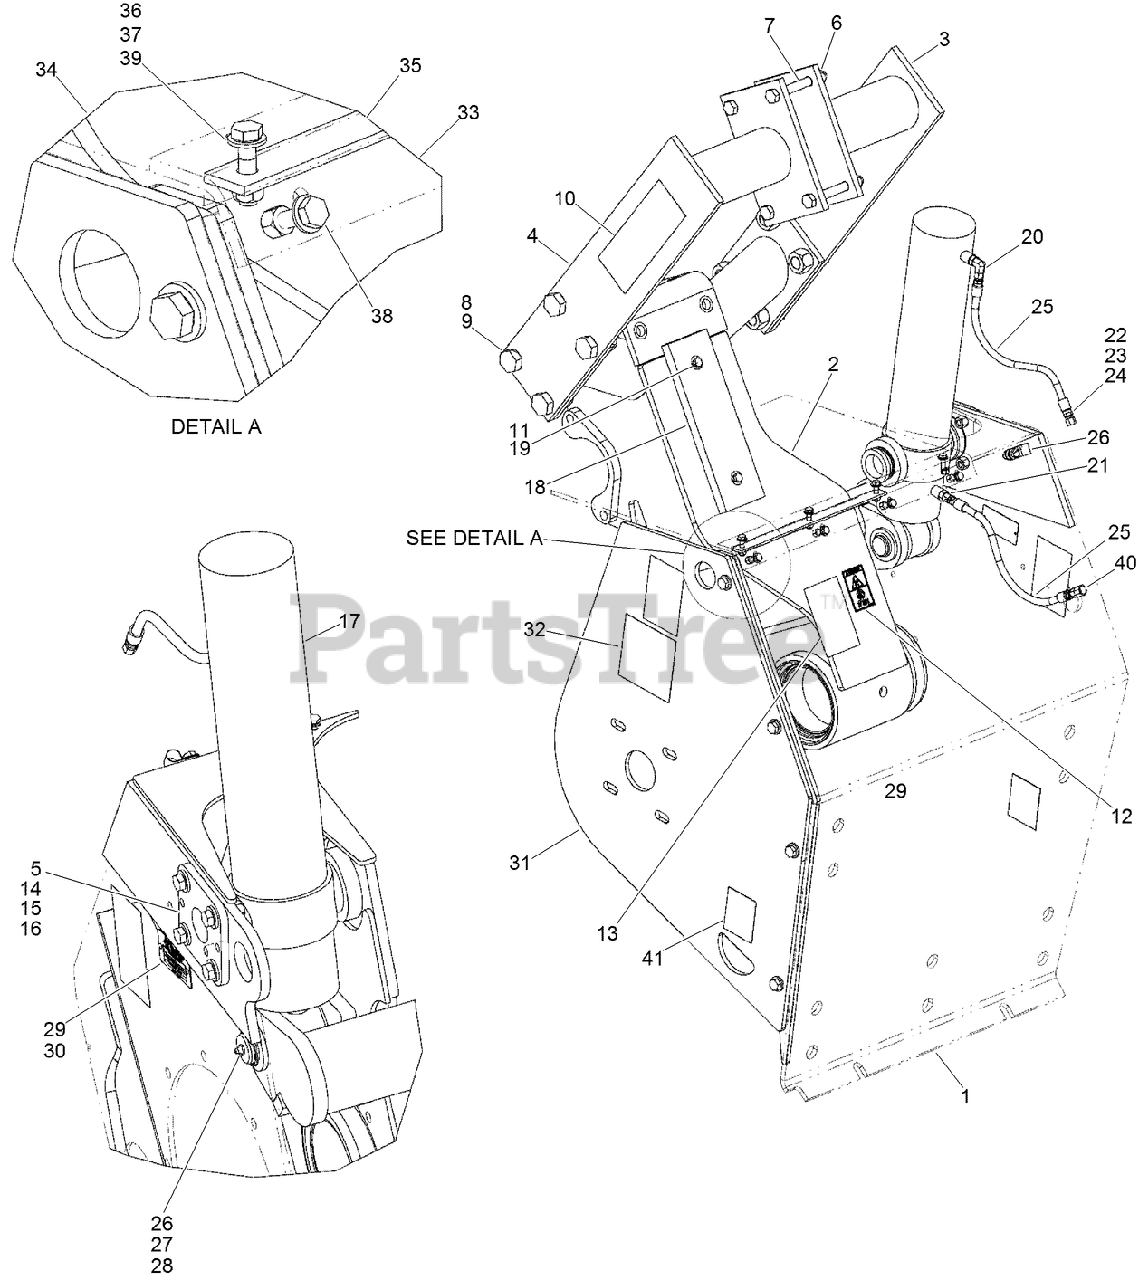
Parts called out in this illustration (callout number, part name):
1	WELDMENT - Trencher Frame
2	WELDMENT - Boom Attach
3	WELDMENT - Crumber Mounting
4	WELDMENT - Crumber Mounting
5	PIVOT BLOCK ASM
6	NUT-LOCK, HEX
10	DECAL-Danger, Trencher Entanglement Hazard
11	NUT-SQUARE
12	DECAL-Warning, Call Before Digging
13	DECAL-Danger, Trencher Entanglement Hazard
15	SCREW-HH
16	NUT-HEX
17	CYLINDER - Boom Lift (4 inch)
18	STRIP - Wear, Long
19	SCREW-HH
20	ELBOW-90 DEG (ADJUSTABLE 37 DEG)
21	CONNECTOR-Str Thd 3/8, 37FL-ORB 3/8
23	SCREW-HH
24	NUT-Serr Flg 3/8-16 UNC GR5 ZND
25	HOSE-Trencher Lift
26	PIN-PIVOT
28	FITTING-Lube 1/8-27 Dryseal PTF
29	PLATE - Serial Number
30	TACK-FASTENER, STEEL
31	WELDMENT - Bearing Support Plate
32	DECAL-Planetary Oil / Lube Lever
33	ANGLE - Dirt Deflector Mounting
34	DEFLECTOR-DIRT
35	STRIP-DIRT DEFLECTOR
36	WASHER-FLAT
37	NUT-HEX
38	SCREW-HH
39	BOLT-Hex, 5/16 NC x 1-1/4 inch
40	ORIFICE - 0.047 Inline
41	DECAL-Tie Down
